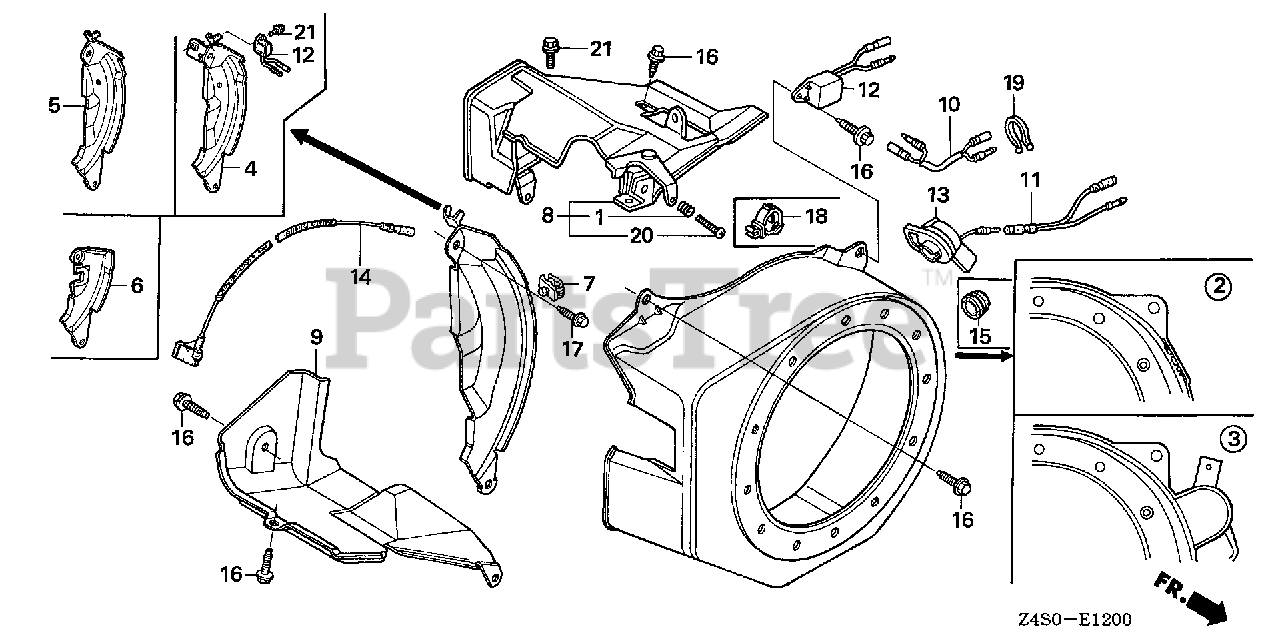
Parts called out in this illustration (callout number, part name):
2	COVER, FAN *R280* (POWER RED)
4	PLATE, SIDE (OIL ALERT)
9	SHROUD
12	ALERT UNIT, OIL
13	SWITCH ASSY., ENGINE STOP
14	WIRE, STOP SWITCH (370MM)
16	BOLT, FLANGE (6X12) (CT200)
17	BOLT, FLANGE (6X20) (CT200)
18	CLIP, HARNESS
21	BOLT, FLANGE (6X8)
